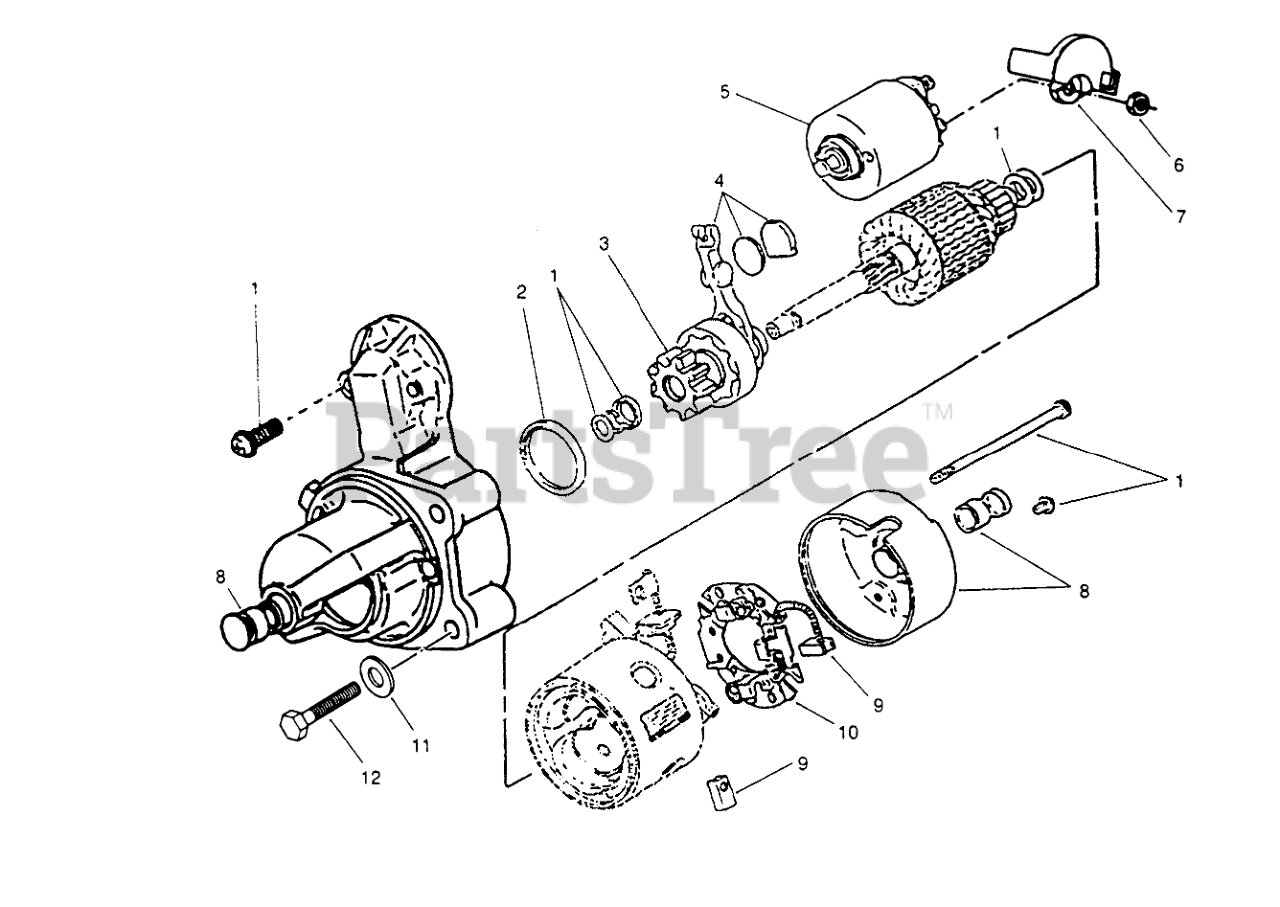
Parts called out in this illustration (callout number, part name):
1	Kit-Hardware, Starter (Incl. Solenoid Screws, Brush Holder Screws, Thru Bolts, Shims, Pinion Stop Collar, & Pinion Retaining Rings)
2	DUST-SEAL KIT
3	CLUTCH STARTER ASSEMBLY
4	LEVER
5	STARTER SOLENOID KIT
6	Nut-Hex.
7	Cap-Starter Solenoid
8	Kit-Bushing, Starter (Incl. Rear Cap, Front & Rear Bushings)
9	Kit-Brush, Starter (Incl. Ref. #10)
10	Holder-Brush, Starter
11	WASHER
12	SCREW-HH
13	KIT-MTG BRKT
14	WASHER
